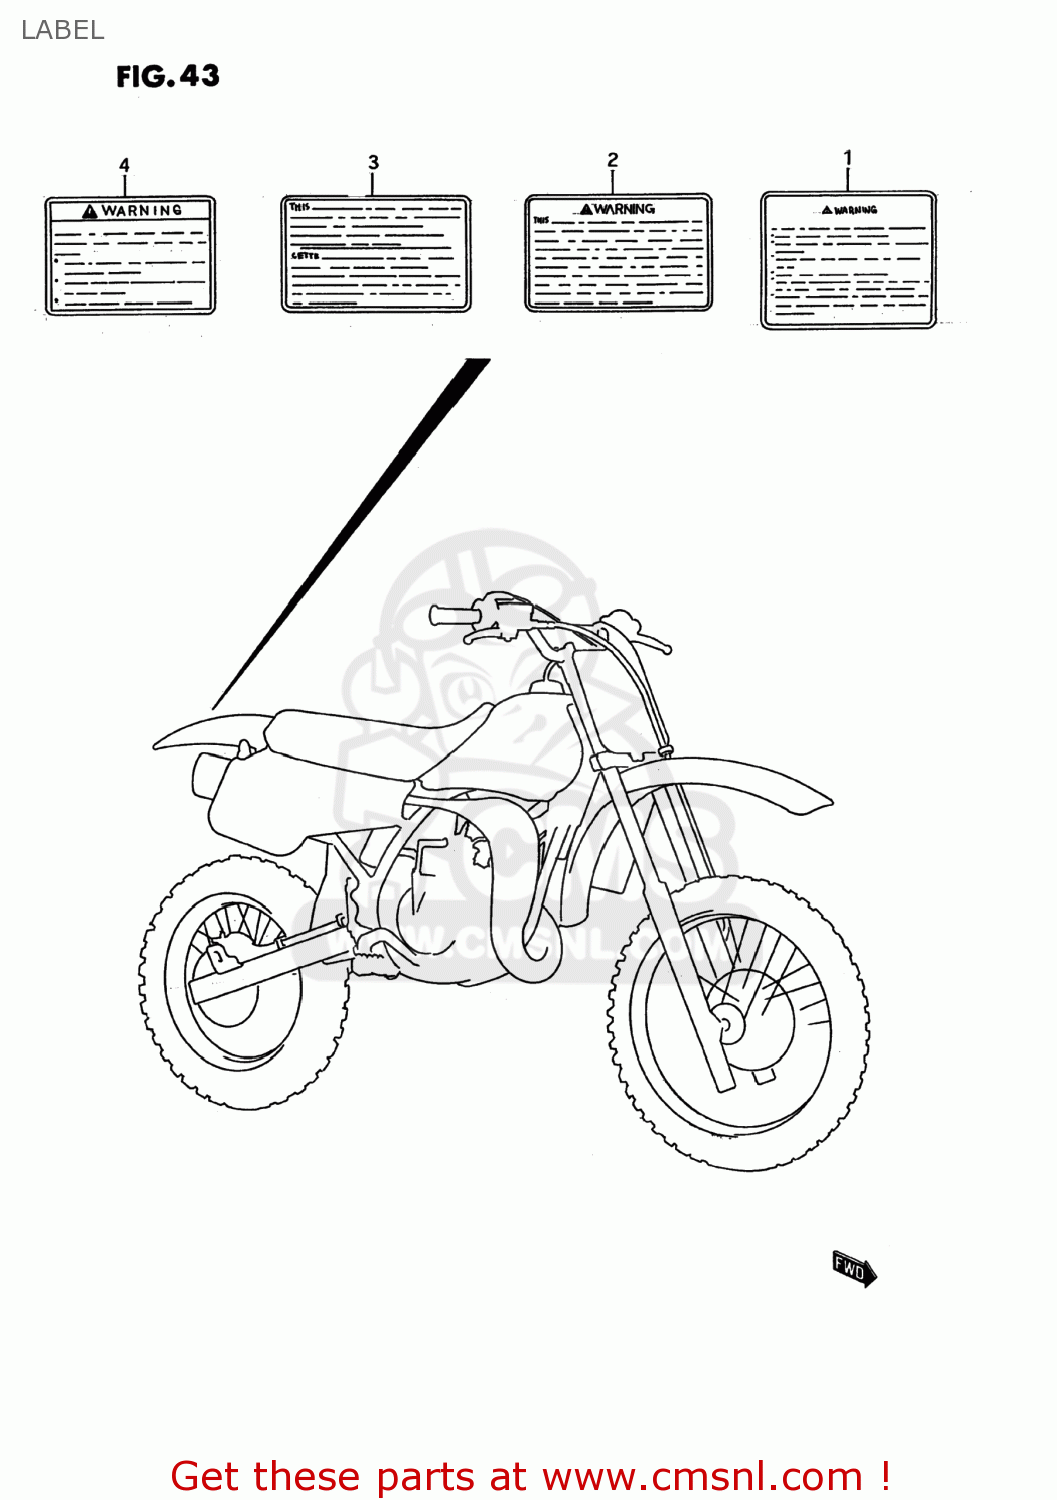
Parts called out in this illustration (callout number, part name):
1	LABEL,WARNING
2	LABEL,WARNING
3	LABEL,WARNING
4	LABEL
5	MANUAL, OWNER'S
